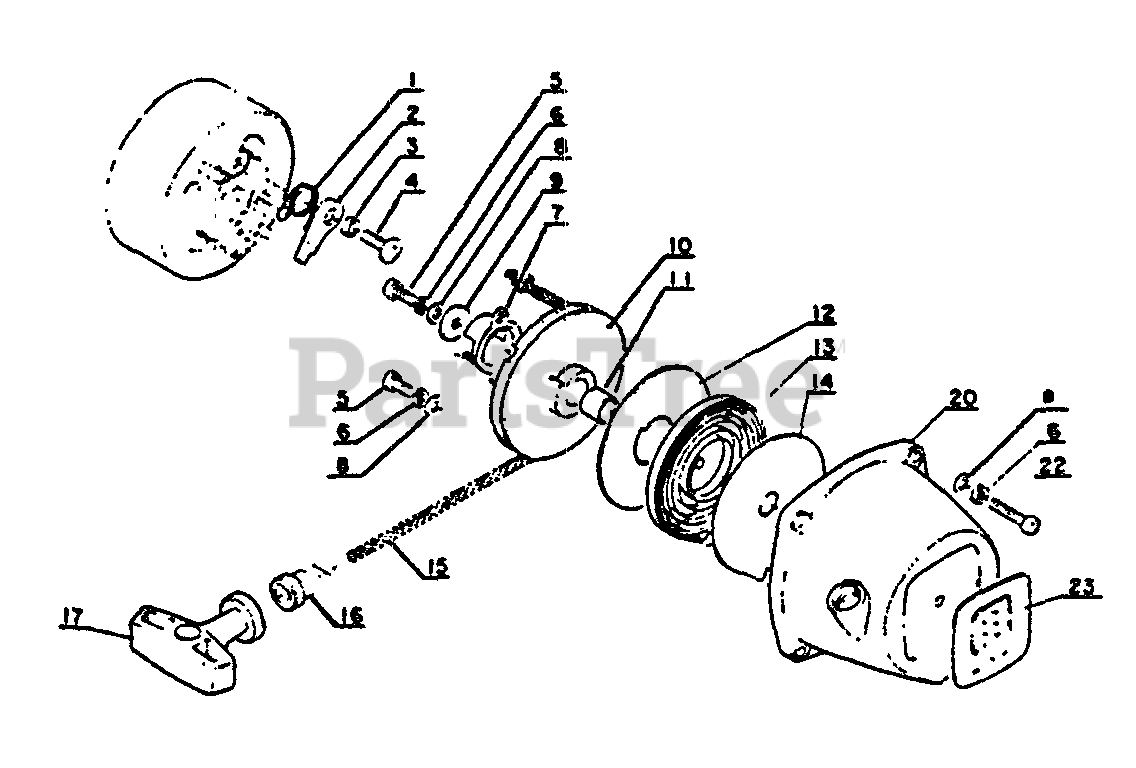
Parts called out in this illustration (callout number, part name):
1	SPRING, RETURN
2	PAWL, STARTER
4	SCREW
4	STARTER ASSY
5	SCREW - 4X10
6	LOCKWASHER - 4
7	CATCHER, PAWL
8	WASHER - 4
10	REEL, ROPE
12	PLATE, STARTER
13	SPRING, REWIND
14	PLATE, STARTER
15	ROPE, STARTER - 3.5X850
16	GUIDE, ROPE
17	GRIP, STARTER
20	CASE, STARTER
22	SCREW - 4X20
23	LABEL - ECHO
